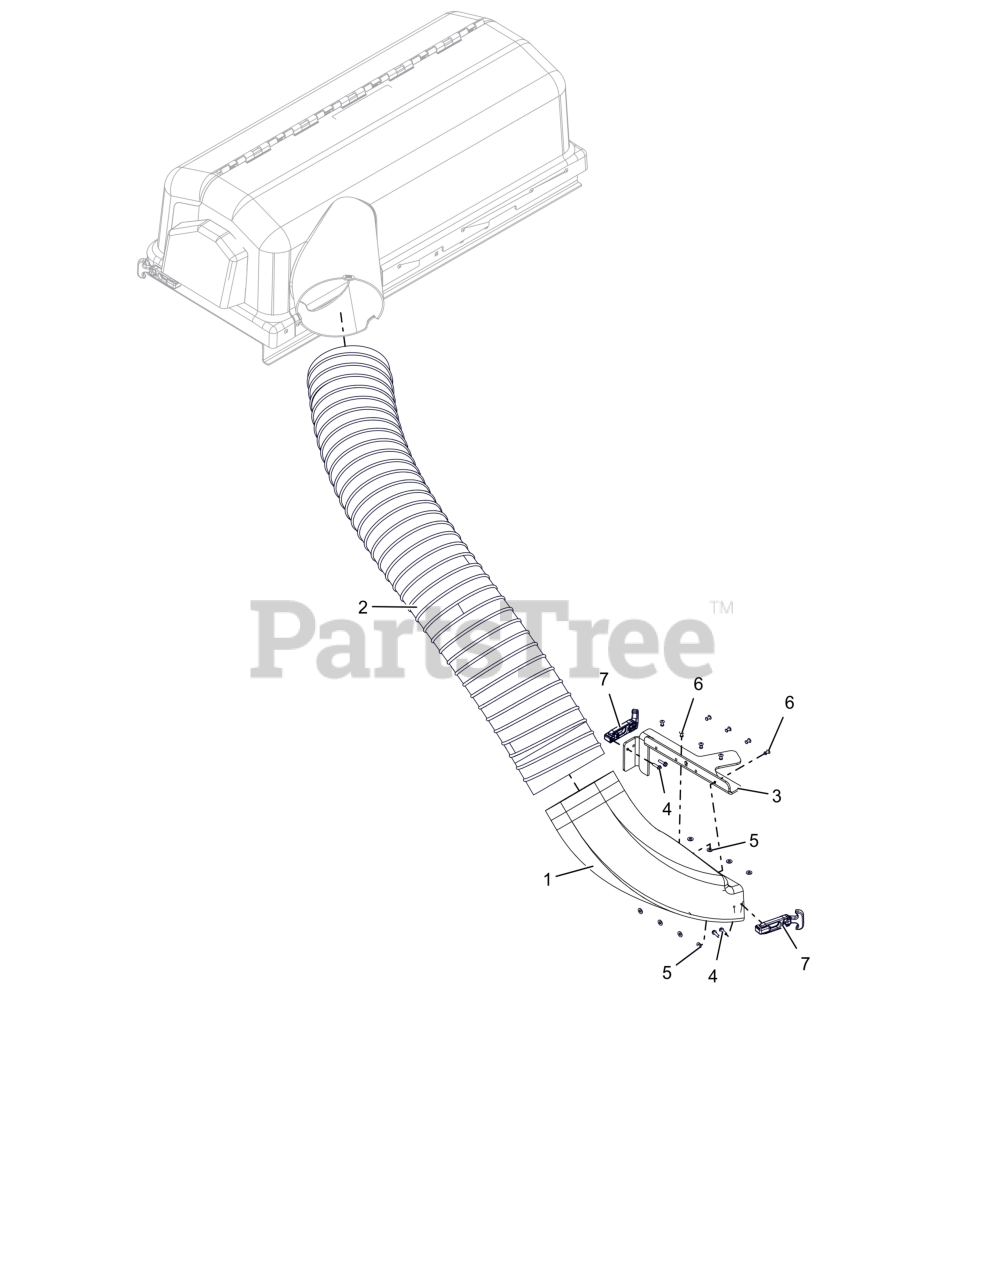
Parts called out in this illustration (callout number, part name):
1	KIT, 34" BOOT ASSEMBLY
2	HOSE, FLEXIBLE-47"
3	BRKT, BOOT 34" ZOOM/ZT
4	@SCR-MCH 10-24X.75 HWH YWZC
5	WSHR, FLT .219X.500X.049 ZCC
6	RVT-POP.187X.527 DOME ST
7	LATCH, RUBBER
